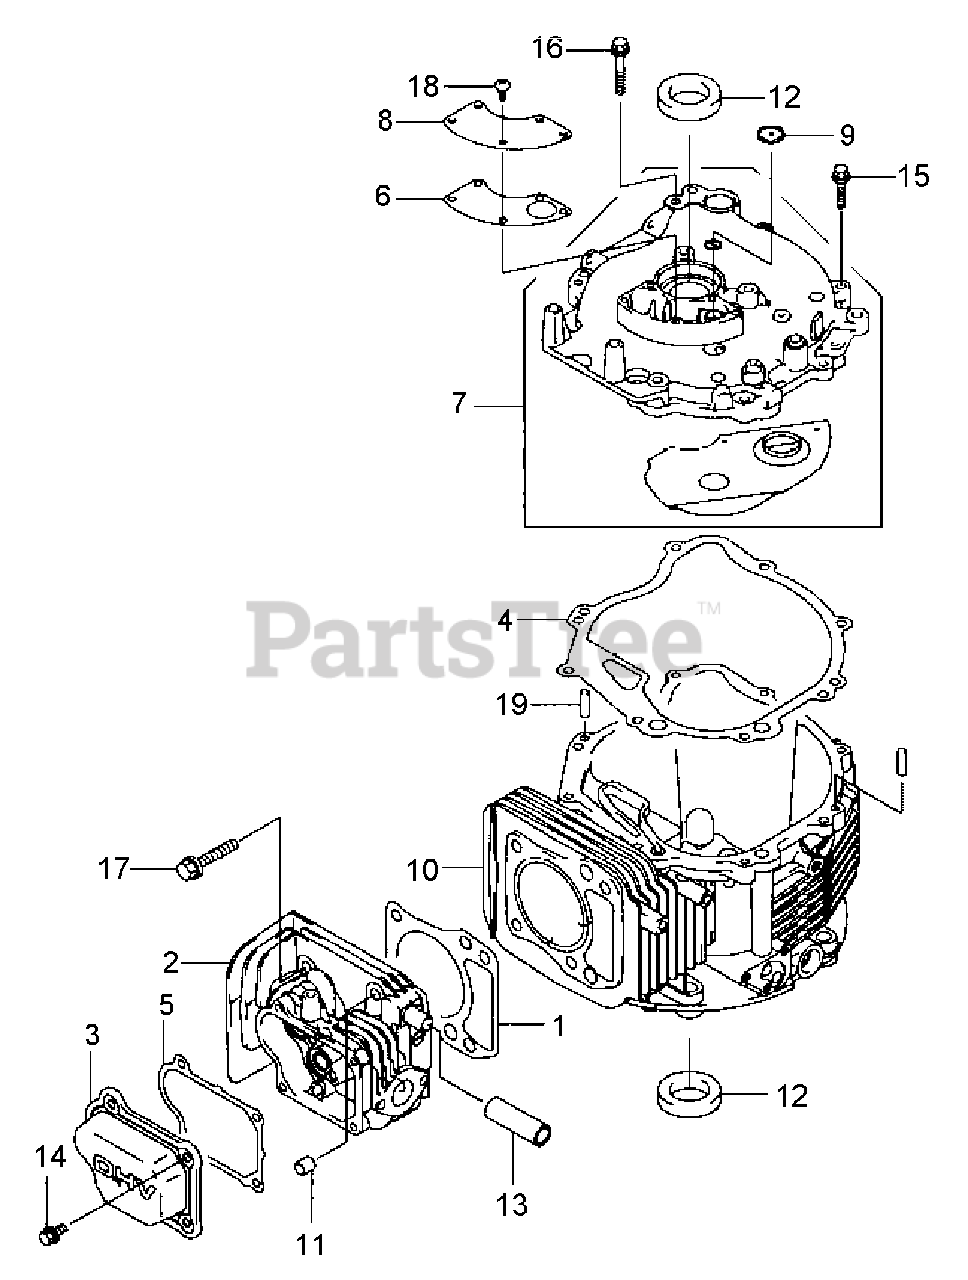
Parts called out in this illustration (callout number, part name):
1	Head Gasket
2	Cylinder Head
3	Rocker Case
4	Cover Gasket
5	Rocker Case Gasket
6	Breather Gasket
7	Cover-Complete
8	Breather Cover
9	Breather Valve
10	Crankcase-Complete
13	Tube, 12x16x49
14	Flanged Bolt
15	Flanged Bolt
16	Flanged Bolt
17	Flanged Bolt
